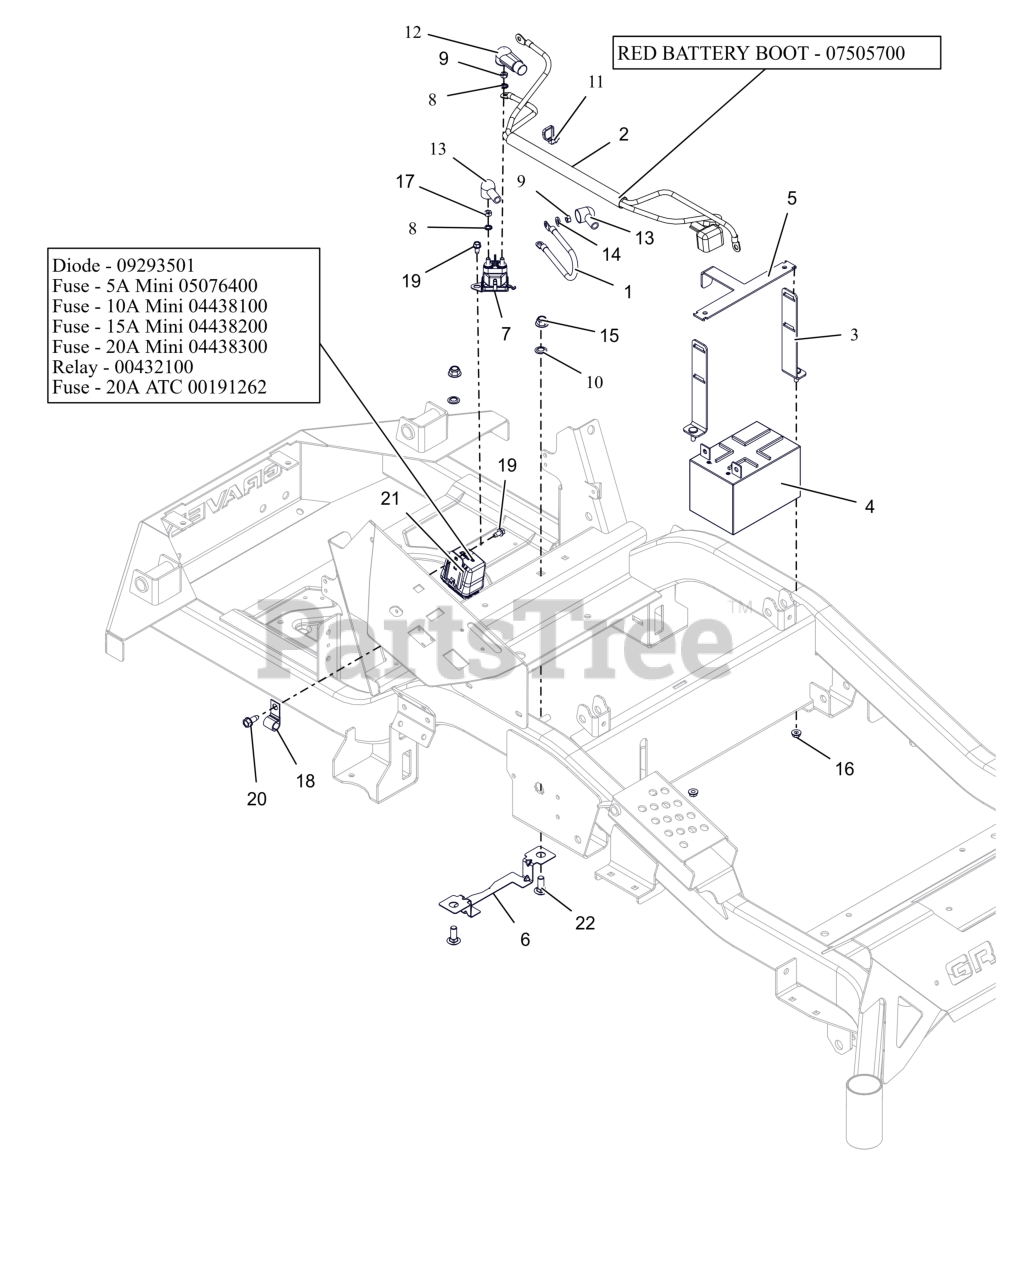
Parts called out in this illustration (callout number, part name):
1	CABLE, POS W/(2)1/4 RING 9.0LG
2	HARNESS, BATTERY HD
2	INSULATOR
3	WMT,BATTERY MOUNT HOLD DOWN
4	BATTERY, 12V 12A-190CCA
5	BRKT, BATTERY TIE DOWN
6	GUARD, ELECTRICAL HARNESS
7	SOLENOID, STARTER (SEALED)
8	WSHR,LK-EXT.262X.502X.026 ZCC
9	NUT-STD M6-1.0 ZCC
10	NUT-PUSH .38 DIA. PAL ZINC
11	CABLE TIE W/ TREE (.25 HOLE)
12	BOOT, .65ID POS
13	BOOT, EYELET TERMINAL
14	WSHR,LK-REG .312X.078 ZCC
15	NUT,NYL-FLG .38-16 GF ZCC
16	NUT-LK-TOP-FLG .250-20 GF ZCC
17	NUT-STD M6-1.0 ZCC
19	SCR-TAP .25-20X.50 HWH ZCC
20	SCR,TAP .312-18X.75 HWH TR ZCC
21	HARNESS, WIRE
21	DIODE, CONNECTOR SHELL
21	FUSE, 5 AMP MINI-ATC
21	FUSE,10 AMP MINI-ATC
21	FUSE,15 AMP MINI-ATC
21	RELAY,SEALED W/DIODE
21	FUSE,20 AMP MINI ATC
21	FUSE, 20 AMP BLADE S/O
22	BLT, RHSN .38-16X1.00 G5 ZCC
